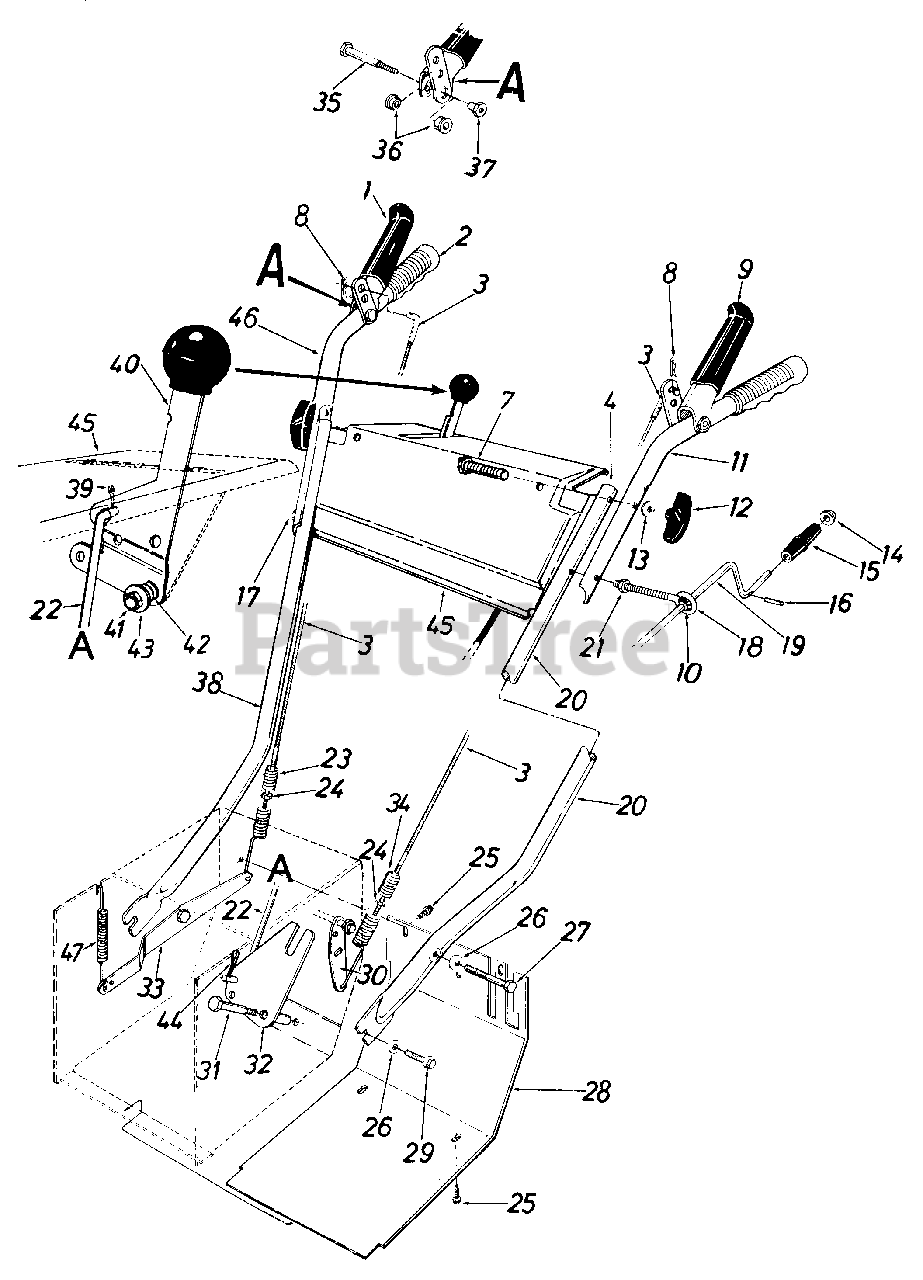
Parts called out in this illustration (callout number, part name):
1	Clutch Grip Ass'y. R.H.
2	Grip
3	Lockout Cable 30.5" Lg.
4	Plastic Plug
7	Hex Bolt 5/16-18 x 2.00" Lg.
8	Hairpin Cotter
9	Clutch Grip Ass'y. L.H.
10	Plastic Bushing
11	Upper Handle Half L.H.
12	Hand Knob
13	Bell-Wash. .345" I.D. x .88" O.D. x .060
14	Cap Speed Nut for 3/8" Rod
15	Knob 3/8" Rod
16	Roll Pin .12 Dia. x .631" Lg.
17	Carr. Bolt 5/16-18 x 2" Lg.
18	Eyebolt
19	Chute Crank Ass'y.
20	Lower Handle Half L.H.
21	Hex Nut 5/16-18 Thd.
22	Shift Rod
23	Ext. Spring .75" O.D. x 5.00" Lg.
24	Hex Ins. L-Nut 1/4-20 Thd.
25	Hex Wash. Hd. Self-Tap Scr. 5/16-24 x .50" Lg.
26	Bell-Wash. .401" I.D. x .88" O.D. x .060
27	Hex Bolt 3/8-16 x 2.00" Lg.
28	Frame Cover
29	Pilot Scr. 3/8-16 x .88" Lg.
30	Drive Clutch Brkt. Ass'y.
31	Shld. Bolt .498 Dia. x 2.005
34	Spring
35	Shld. Bolt .374" Dia. x 1.53" Lg.
36	Hex Flange Brg. Plastic .38" I.D.
37	Shld. Nut 1/4-20 Thd.
38	Lower Handle Half R.H.
39	Hairpin Cotter
40	Shift Handle Ass'y.
41	Hex Ins. Jam L-Nut 3/8-24 Thd.
42	Comp. Spring .60" O.D. x .88" Lg.
43	Bell-Wash. .401" I.D. x .88" O.D. x .060
44	Cotter Pin 3/32" Dia. x .75" Lg.
45	Handle Panel Ass'y.
46	Upper Handle Half R.H.
47	Ext. Spring .38" O.D. x 3.18"
